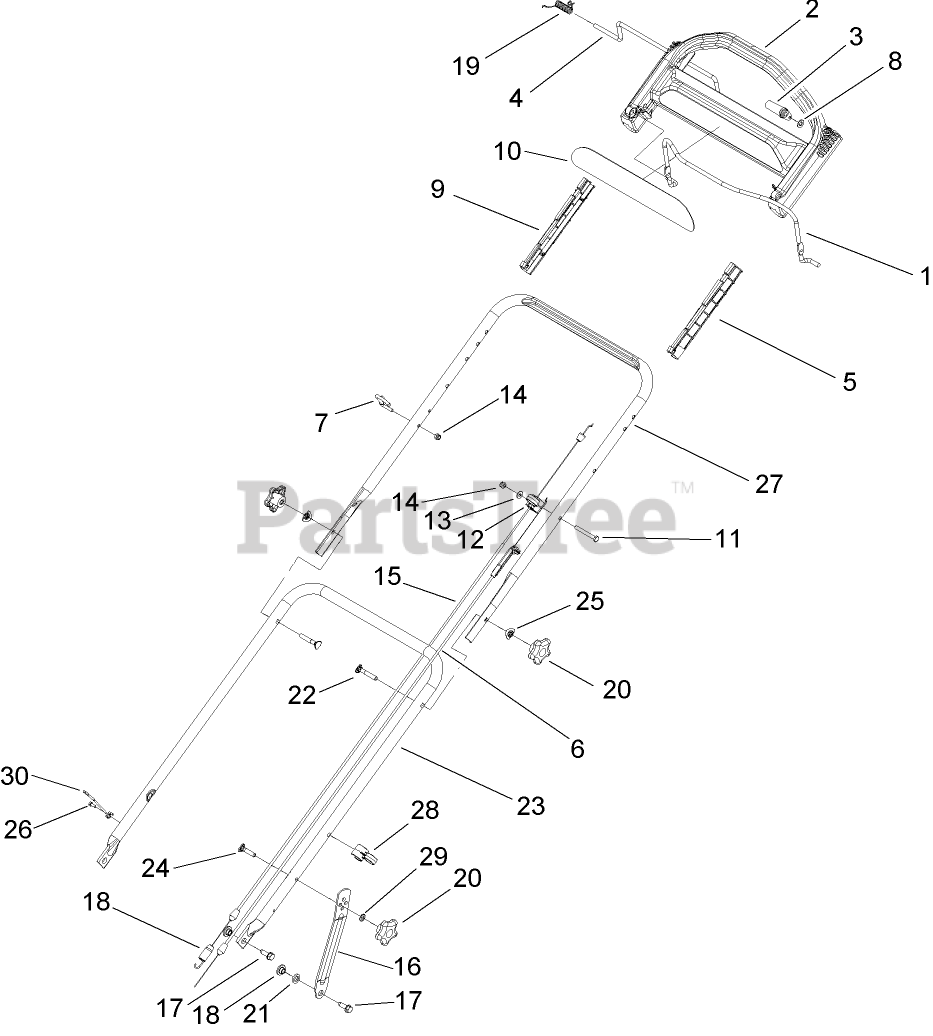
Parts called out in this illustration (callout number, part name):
2	HANDLE-CONTROL
3	LEVER-TRACTION
5	GUIDE-LH
6	CABLE-BRAKE
7	GUIDE-ROPE
8	WASHER-PLAIN
9	GUIDE-RH
10	DECAL-HANDLE
11	SCREW
13	WASHER-FLAT
14	NUT-LOCK, NI
15	CABLE-TRACTION
16	SUPPORT-HANDLE
17	SCREW-THD ROLL, HWH
20	KNOB-HANDLE
21	WASHER
22	SCREW-HANDLE
23	HANDLE-LOWER
24	SCREW-HANDLE
25	WASHER
26	SCREW-SHWH, THREAD FORMING
27	HANDLE-UPPER
29	WASHER-LOCK
30	HOOK-ROPE, DISPLACEMENT
